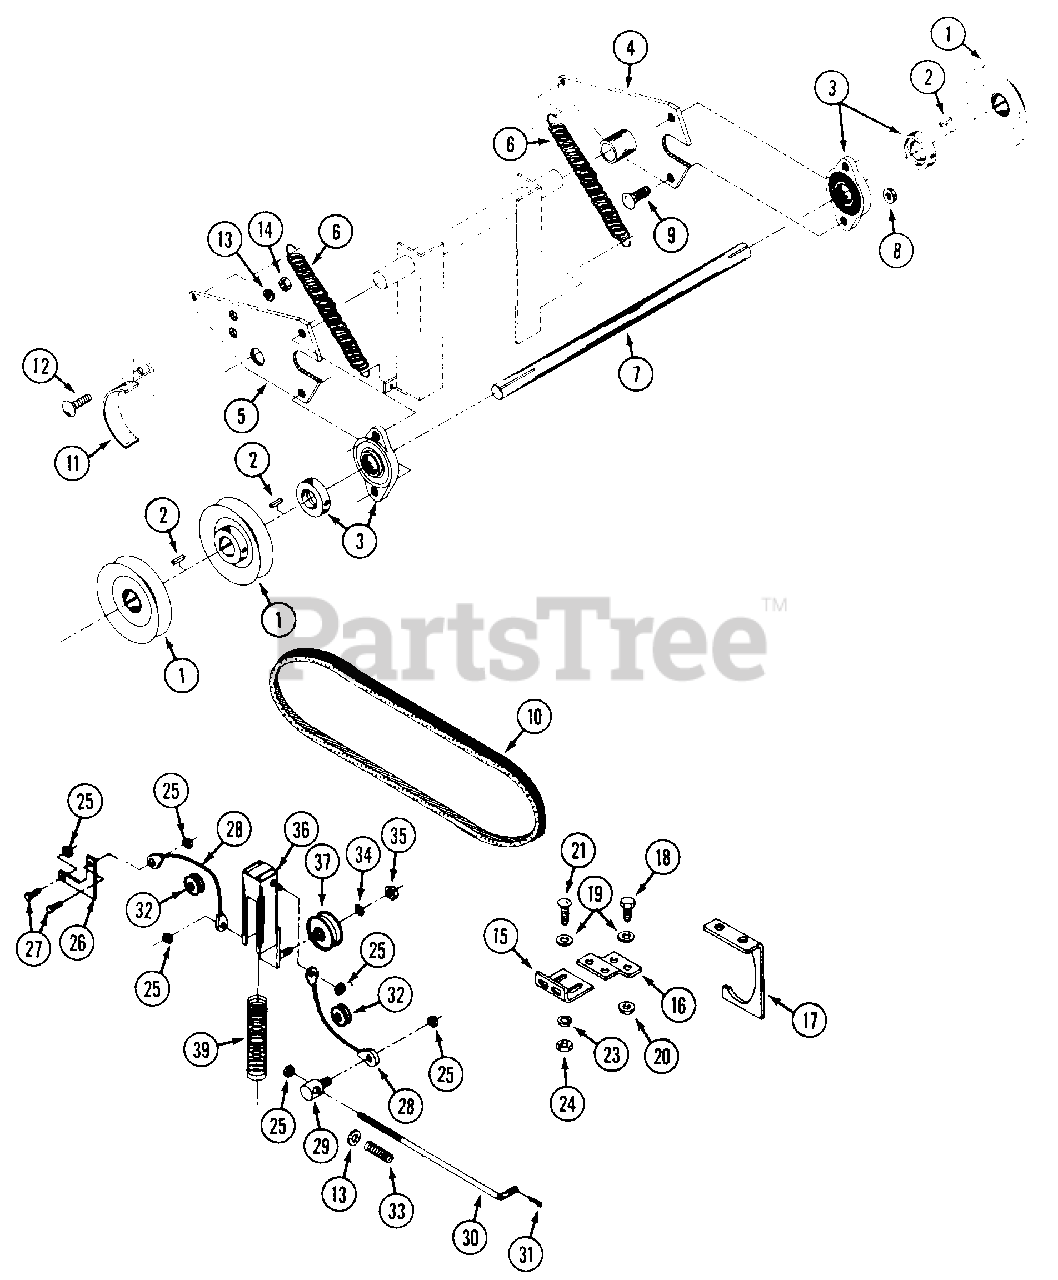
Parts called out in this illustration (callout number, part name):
1	PULLEY - 4" OD x 3/4" ID
2	KEY - 3/16" x 3/16" x 1"
3	BEARING - flanged
4	MOUNT - bearing L.H.
5	MOUNT - bearing R.H.
6	SPRING - extension
7	SHAFT - cross
8	NUT - 5/16-18 flange lock
9	BOLT - 5/16"-18 x 1" carriage
10	BELT - drive
11	RETAINER - cross shaft belt
12	BOLT - 1/4"-20 x 3/4" carriage
13	WASHER - 1/4"
14	NUT - 1/4" - 20 flange lock
15	BRACKET - engine belt retainer
16	BRACKET - engine belt
17	RETAINER - engine belt
18	BOLT - 1/4" - 20 x 3/4"
20	NUT - 1/4"-20 flange lock
21	BOLT - 1/4"-20 x 1" carriage
23	LOCKWASHER - 1/4"
24	NUT - 1/4"-20
25	NUT - nylock 1/4"-20
26	BRACKET - "L", brake linkage
27	BOLT - 1/4"-20 x 1"
28	CABLE - clutch, brake
29	COLLAR - caliper rod
31	PIN - cotter - 3/32" x 1"
32	PULLEY - 1-1/2" OD
33	SPRING - caliper rod
34	LOCKWASHER - 3/8"
35	NUT - 3/8"-16
36	TUBE - drive idler
37	PULLEY - idler 2-1/4" O.D.
39	SPRING - belt tightener
